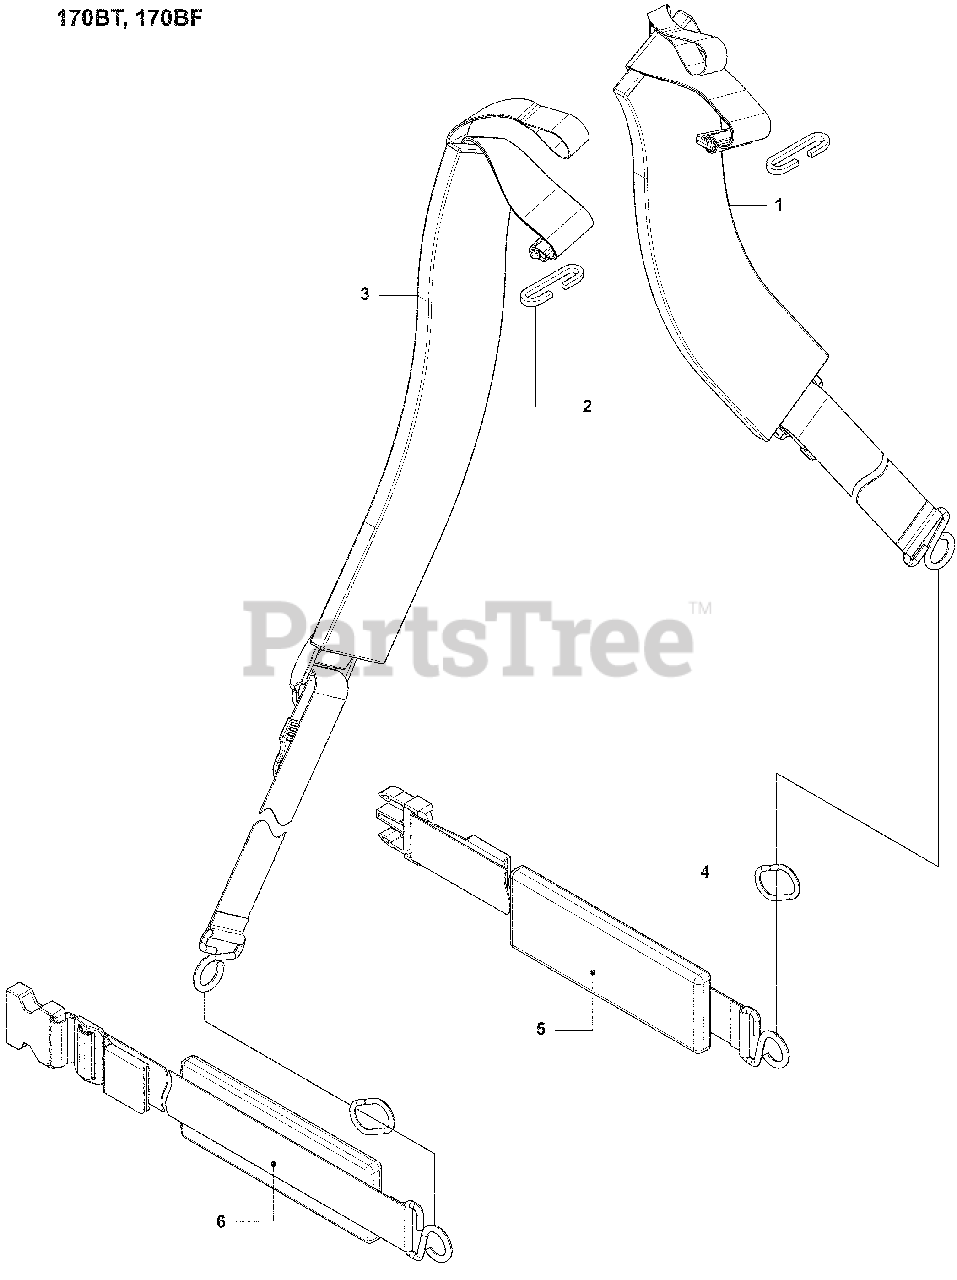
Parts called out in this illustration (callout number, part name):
1	Shoulder Strap, RH
3	Shoulder Strap, LH
4	Ring
5	Shoulder Strap, RH
6	Shoulder Strap, LH
